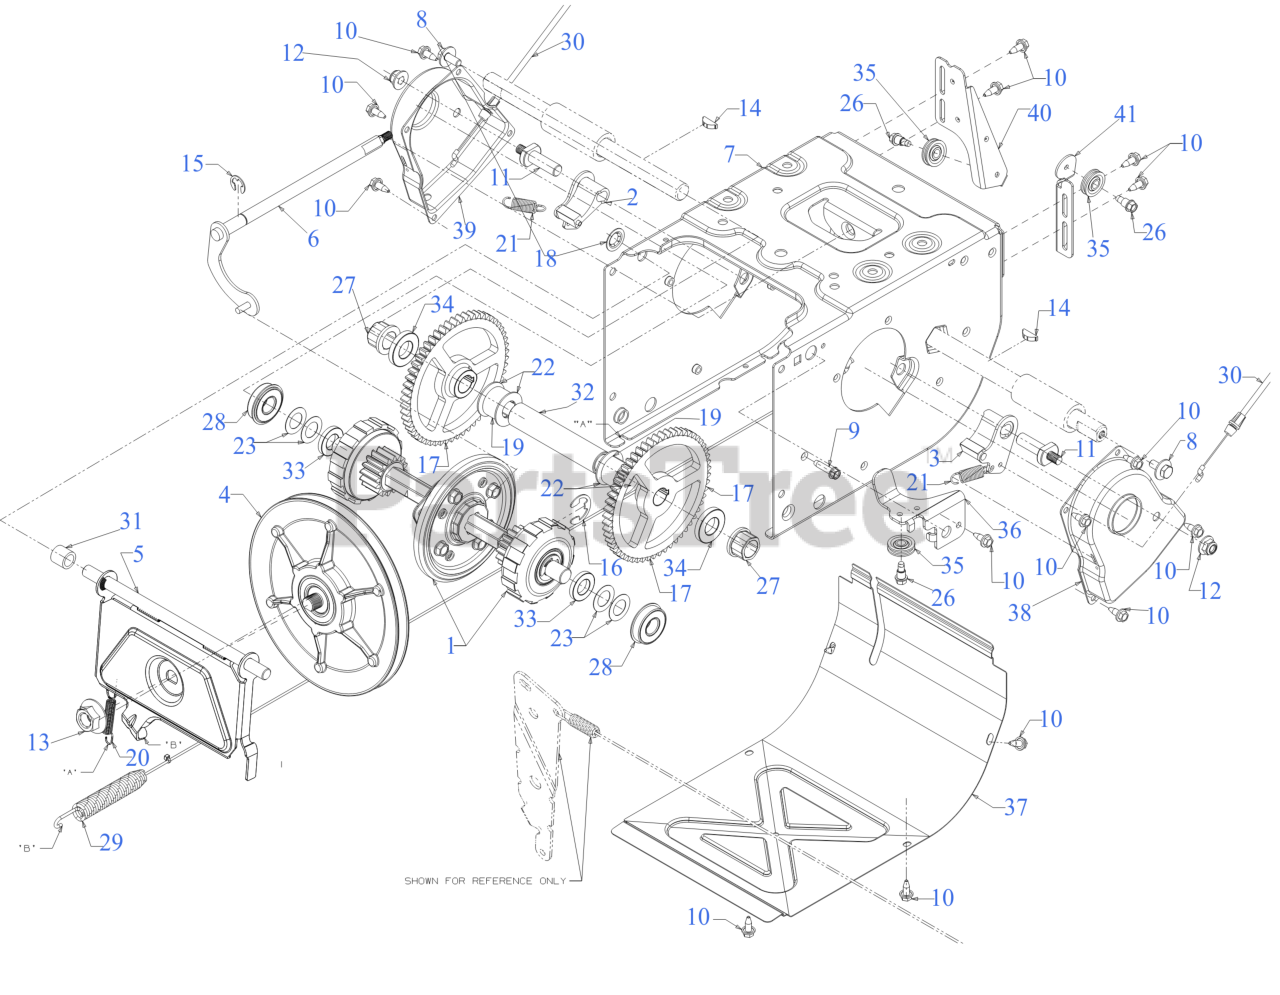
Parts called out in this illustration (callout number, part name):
1	PLANETARY FRICTION WHEEL HEX SHAFT
2	DOGG ASSEMBLY (RH)
3	DOGG ASSEMBLY (LH)
4	FRICTION WHEEL DISC ASSEMBLY
4	FRICTION DISC PIN
4	BALL BEARING
4	FRICTION DISC PULLEY 3LX8.27
5	FRICTION WHEEL BRACKET (POWDER BLACK)
6	SHIFT ROD ASSEMBLY
7	DRIVE FRAME
8	SCREW 5/16-24 x .750 GR5
9	SCREW 1/4-20 x 1.00
10	SCREW 1/4-20X.625
11	ACTUATOR SHAFT
13	FLANGE NUT 5/8-18
14	KEY 3/16 x 3/4
15	E-RING FOR .500 SHAFT
16	RETAINING RING
19	SPACER: .76ID x .75
20	EXTENSION SPRING
21	EXTENSION SPRING
22	FLAT WASHER
23	FLAT WASHER .67X 1.174X .02
26	SHOULDER SCREW
27	FLANGE BEARING
28	BALL BEARING W/RET
29	WHEEL DRIVE CABLE 44.955"
29	EXTENSION SPRING .55 x 6.25
30	STEERING CABLE
31	SPACER-.513 ID x .703 OD x .69
32	AXLE SUPPORT TUBE
34	AXLE SPACER
35	CABLE GUIDE ROLLER
36	AUGER CABLE BRACKET
40	CABLE GUIDE BRACKET (DRIVE)
41	CABLE GUIDE BRACKET (AUGER)
